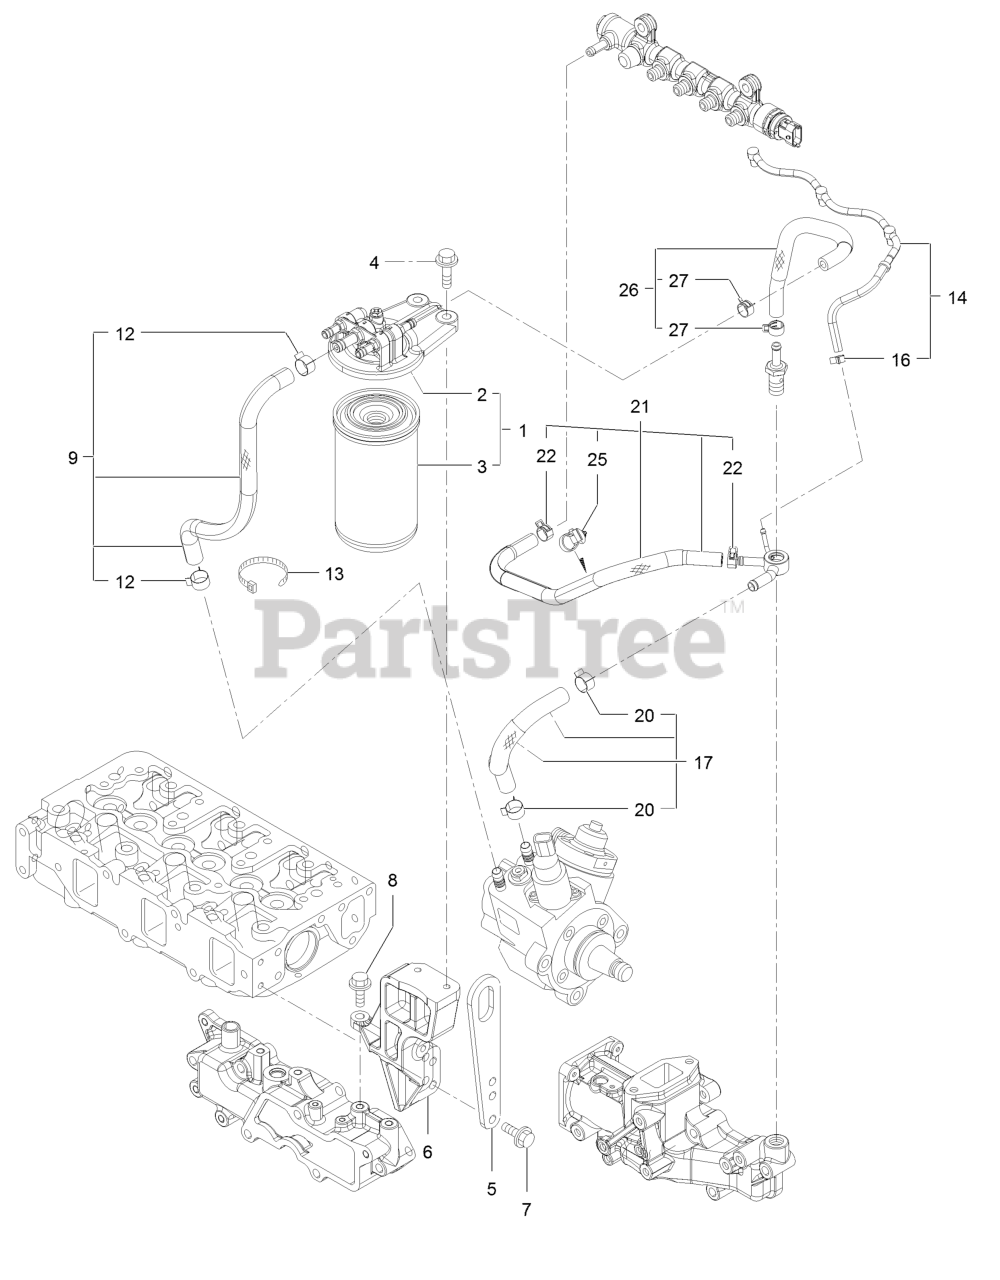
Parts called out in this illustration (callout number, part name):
1	Fuel/Oil Filter ASM
2	Fuel/Oil Filter Bracket ASM
3	Filter-Fuel/Oil
6	Filter Bracket ASM
9	Fuel Pipe ASM
12	Clamp-Hose
14	Pipe ASM-Fo Return
16	Clamp-Hose
17	Fuel Pipe ASM
20	Clamp-Hose
21	Fuel Pipe ASM
22	Clip-Hose
25	Band-Clip
26	Fuel Pipe ASM
27	Clip-Hose
